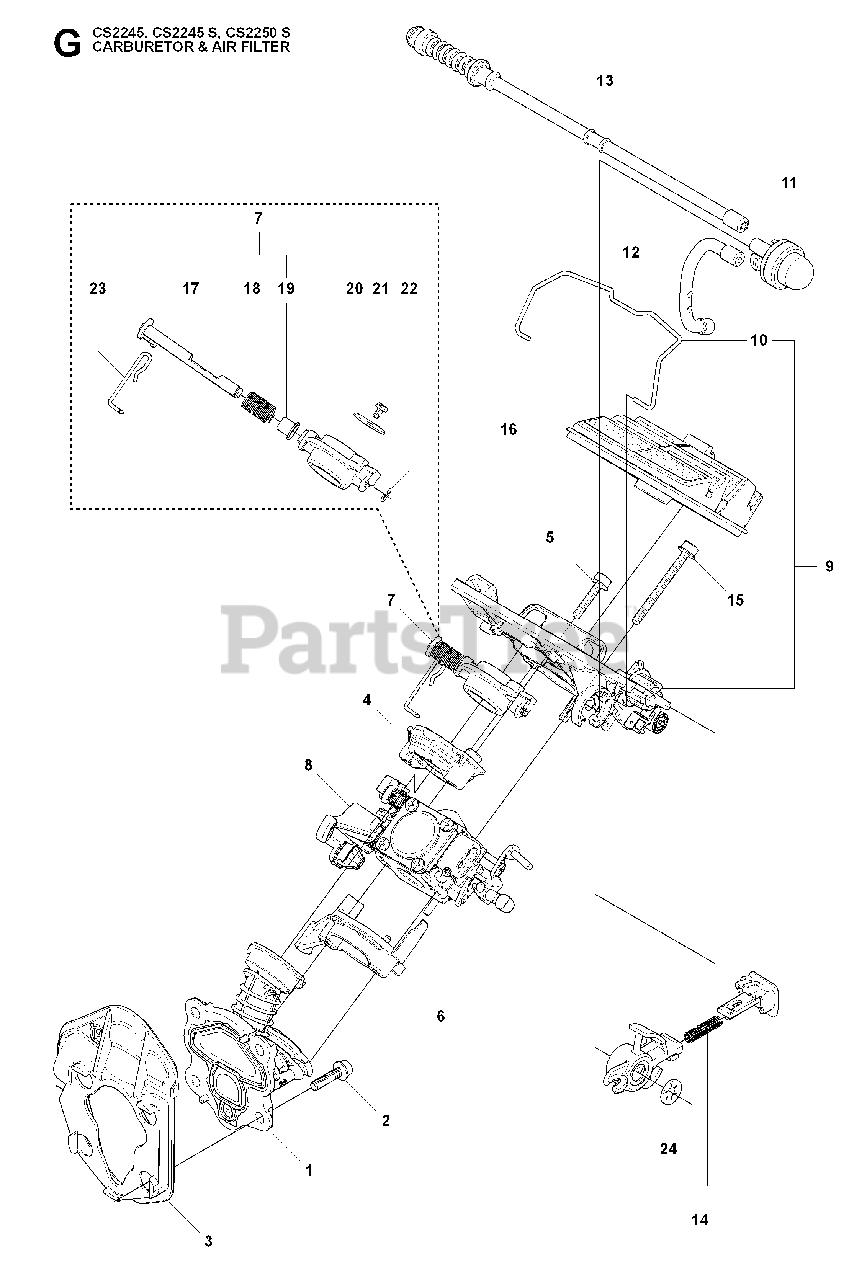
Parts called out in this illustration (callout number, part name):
1	INLET PIPE ASSY
3	INTERMEDIATE WALL
8	CARBURETOR
9	%FILTER HOLDER ASSY
11	AIR PURGE BUBBLE
13	RP RETURN HOSE
16	AIR FILTER - NYLON (80)
16	AIR FILTER - NYLON (44)
16	AIR FILTER - FELT
17	SHAFT ASSY
24	LOCK WASHER
